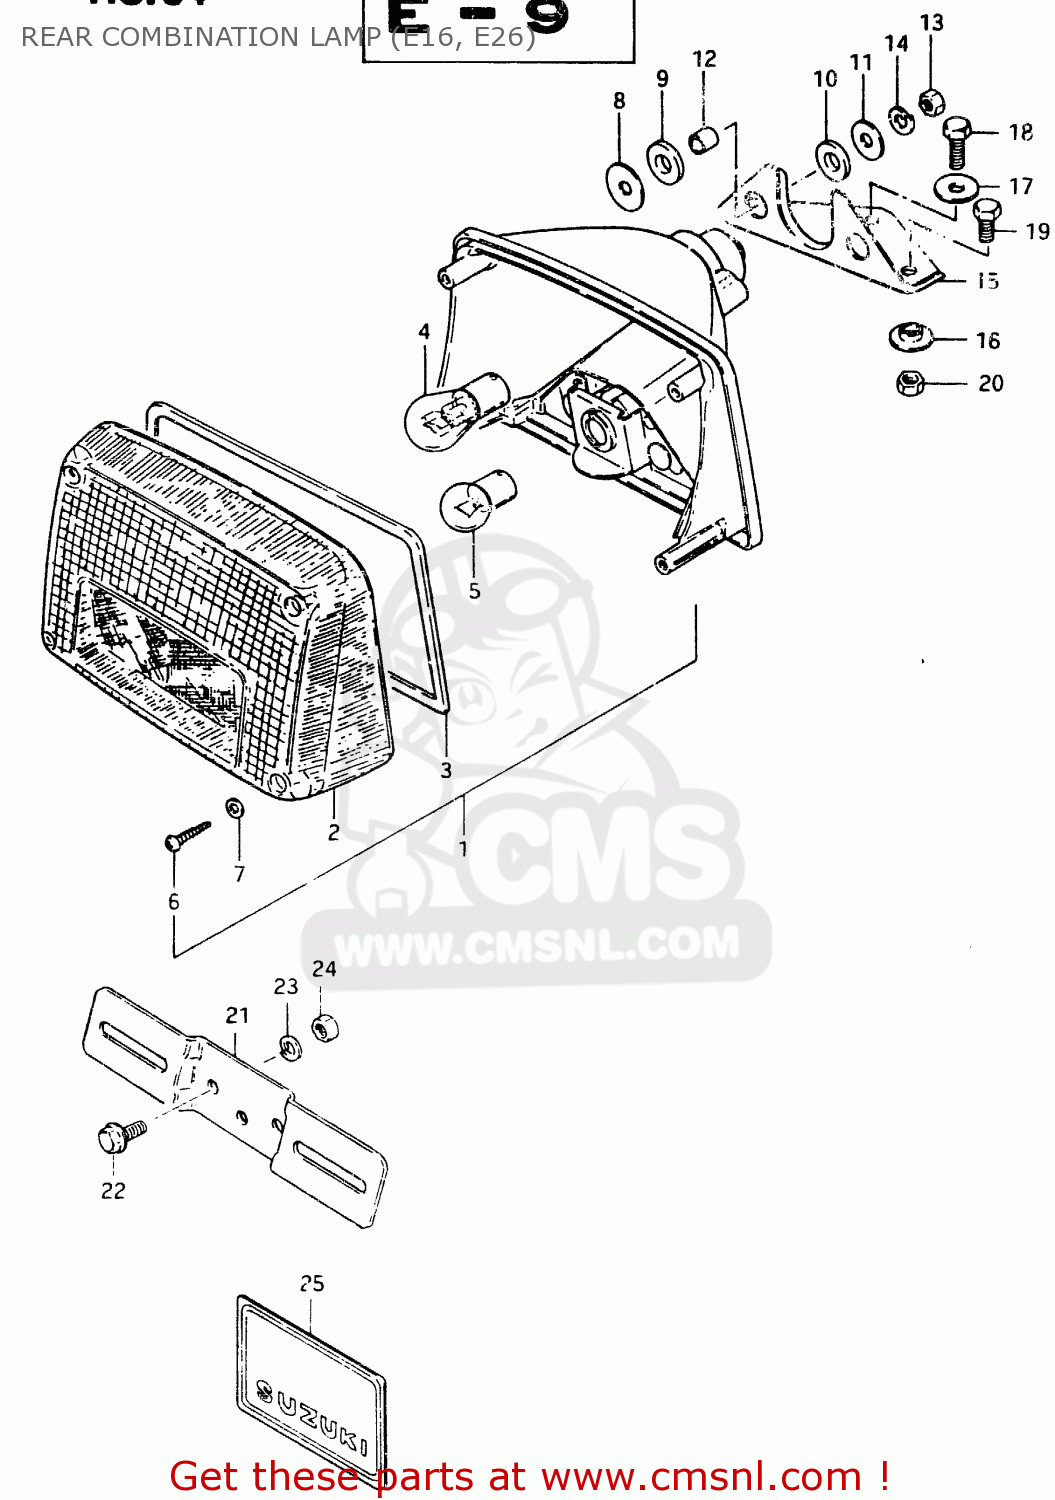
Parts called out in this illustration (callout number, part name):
1	LAMP ASSY, TAIL
2	LENS,RR COMBI
3	GASKET (NAS)
4	BULB 12V21/5W
5	BULB
6	SCREW,REAR COMBINATION LAMP
7	GASKET (NAS)
8	WASHER
9	CUSHION
10	CUSHION
11	WASHER(6,5X22X1.6)
12	SPACER(6.1X9X7.5)
13	NUT
14	LOCK WASHER
15	BRACKET,RR COMBINATION LAMP
16	WASHER
17	WASHER
18	BOLT
19	BOLT, UPPER
20	NUT 6MM
21	BRACKET, LICENSE PLATE
22	BOLT
23	LOCK WASHER
24	NUT
25	EMBLEM, REAR
